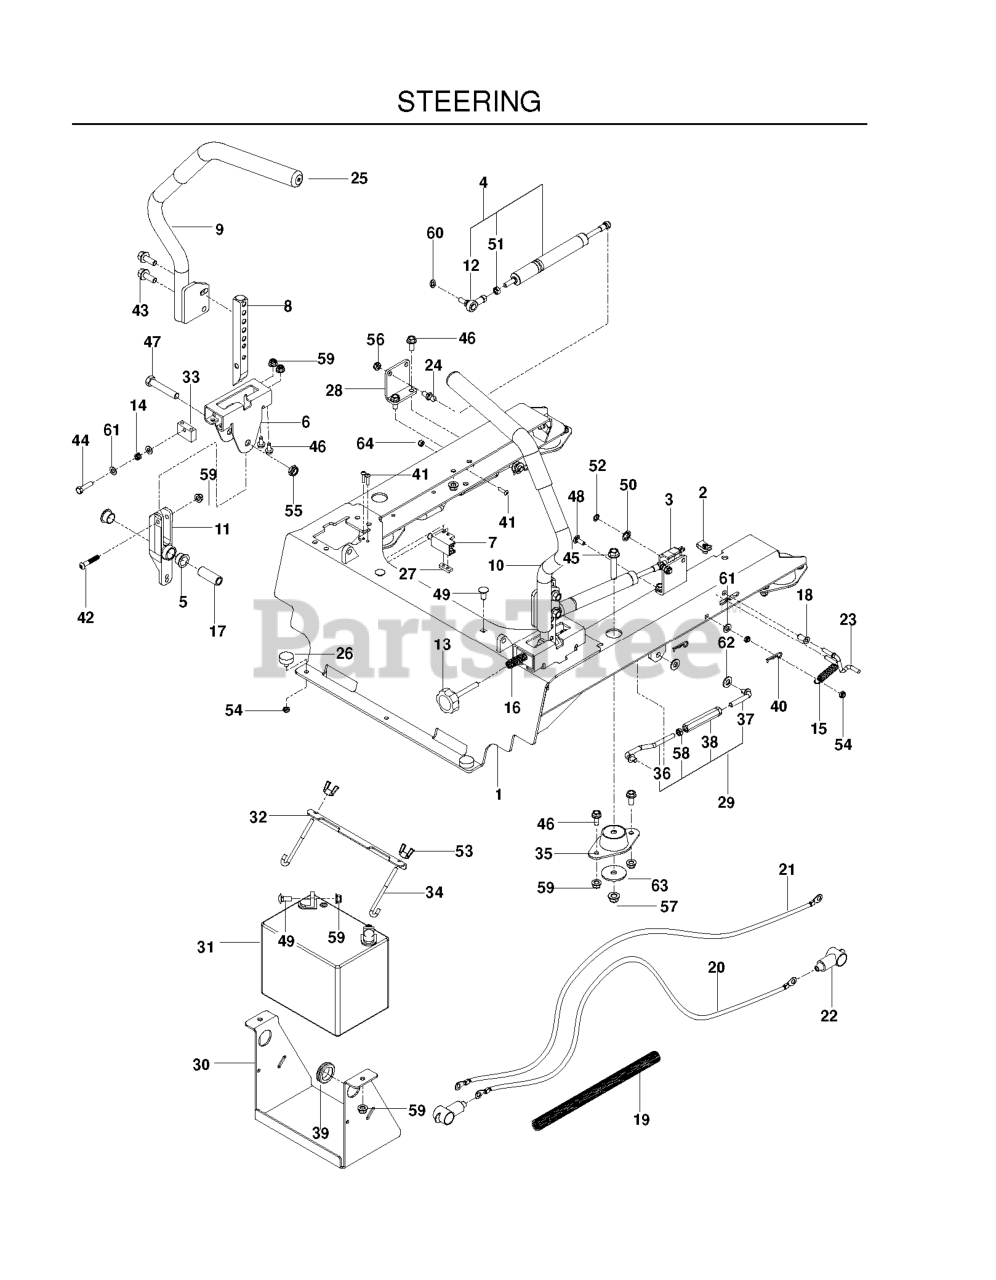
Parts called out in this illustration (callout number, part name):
1	FRAME SEAT MOUNT ORANGE
2	U-CLIP 5/16-18 NUT RETAINER
3	SWITCH, BRAKE 3P
4	ASSEMBLY, DAMPENER
5	BEARING, FLANGE
6	BRACKET, CONTROL
7	SWITCH INTERLOCKT
8	LEVER, MOTION
9	LEVER.WITH GRIP.RT
10	LEVER.WITH GRIP.LT
11	LEVER.CONTROL.SHORT
15	SPRING, EXTENSION
16	SPRING COMPRESSION 2.0
17	SPACER, PIVOT CONTROL
18	BUSHING, 1/4 FLANGE
19	LOOM, SPLIT, CONVOLUTED
20	CABLE, POSITIVE, 55"
21	CABLE, NEG, 55"
23	LINK, SWITCH
24	STUD.BALL.10MM
25	GRIP - DRIVE LEVER 12"
26	NUT
27	TAPPED PLATE
28	BRACKET.DAMPNER
29	ASSEMBLY, SEAT STRUT
30	BRACKET, BATTERY, BLK
31	BATTERY, 12 V 330 AMP
32	BRACKET, BATTERY MOUNT
33	BLOCK.TRACKING
35	MOUNT, ISO
38	TURNBUCKLE, 3/8
39	RUBBER GROMMET
40	HAIRPIN #2
41	SCR #10-24 X .75 SKT HD BLK
42	SCREW 5/16-18 X 1 3/4 BTN-HD
43	HHFS 3/8-16 X 1 GRD 5 ZD
44	HCS 5/16C X 1 1/4
45	HHFS 3/8-16 X 2.0 GD 5
46	HHFS 5/16-18 X 3/4
47	HCS 1/2C X 2 3/4
48	RHSNB 1/4C X 3/4
49	BOLT 5/16C X 3/4" CARRIAGE
50	NUT 3/8 PALNUT RTNG BLK PHOS
51	NUT M8 X 1.25 STD HEX
53	WING NUT 1/4
54	JAM NUT 1/4C (2 2 PW01)
55	NUT 1/2-13 HEX JM NYL
56	NUT 5/16 NYLOC
57	NUT 3/8-16 HEX FLG NYLOC ZD
58	NUT 3/8-24 JAM
59	5/16-18 NYLOC FLANGE NUT
60	WASHER.LOCK.HVY.HLCL.SPR.5/16
61	FLAT WASHER 5/16 SAE
62	WASHER 3/8 SAE FLAT
63	WASHER, 3/8 SPEC
64	NUT 10-24 NYLOC
